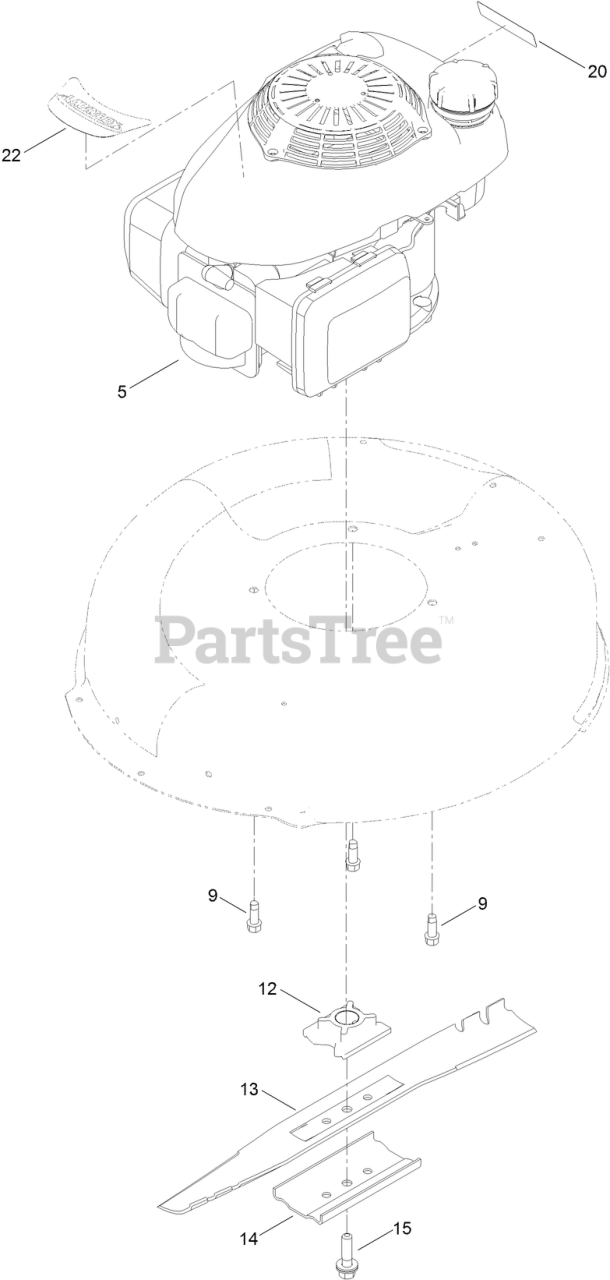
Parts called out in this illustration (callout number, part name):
9	SCREW-TAPTITE
12	RETAINER-BLADE
14	SUPPORT-BLADE
15	BOLT-BLADE
20	DECAL-ARRESTOR, SPARK
22	DECAL-SHROUD, HONDA
